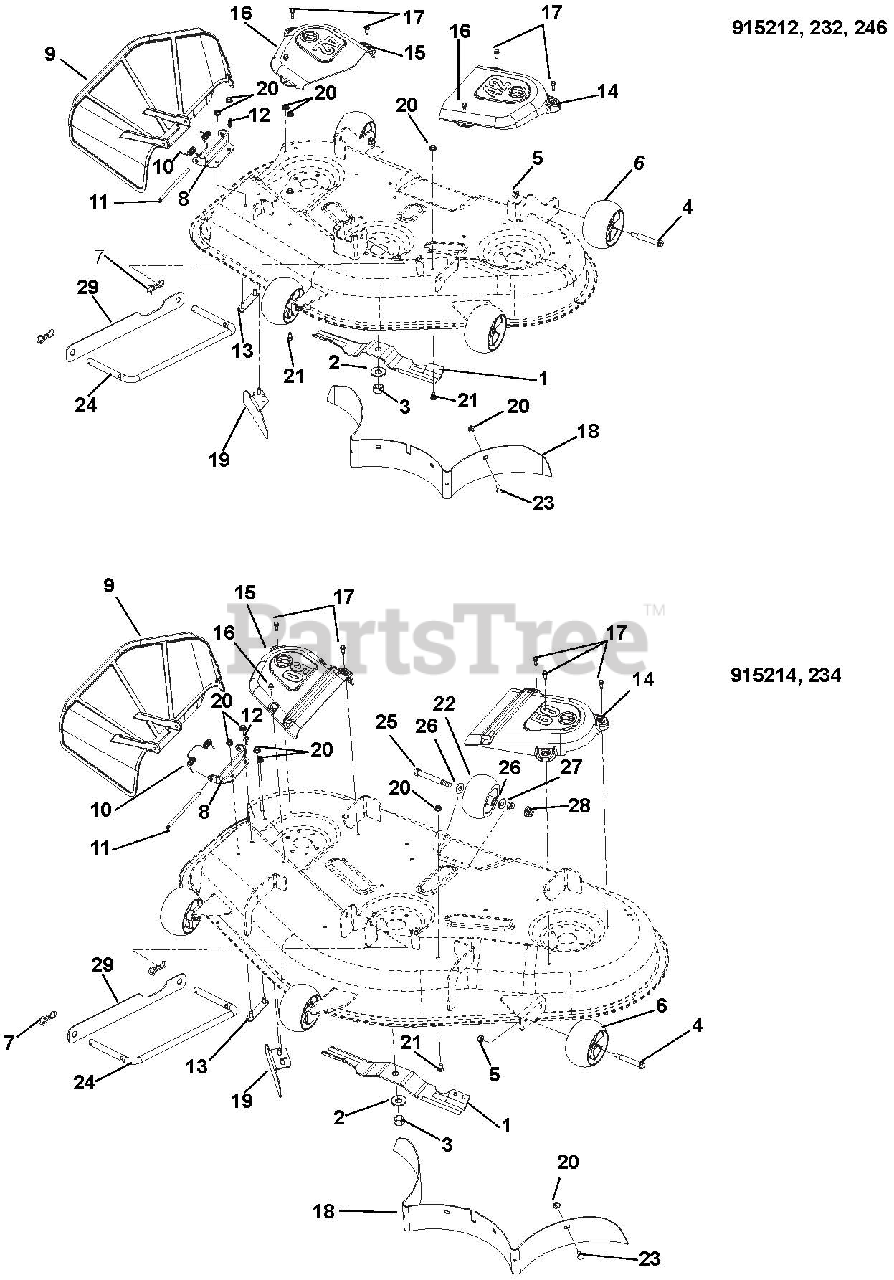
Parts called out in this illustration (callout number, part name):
1	BLADE, MOWER 14.83 (.188 THK)
1	BLADE, MOWER 17.35
2	WSHR-BLVL .669X1.535X.138
3	NUT-HEX .62-18 YWZC
4	BLT-SHLDR .38-16X2.50 HWH G5
5	@NUT-LK-TOP-FLG .38-16 YWZC
6	ANTI-SCALP WHEEL - 5X OS
7	PIN,BOW TIE LOCKING .091X1.875
8	BRKT-DISCHARGE CHUTE MOUNT 42"
8	BRKT, CHUTE MOUNT - 50"
9	CHUTE, DISCHARGE - MOLDED
10	SPRING-TORSION
11	PIN, 5/16 X 5.80"
12	PIN-HAIR INT .08X.18X1.18 YWZC
13	WMT-DISCHARGE CHUTE MT. STRAP
14	BELT COVER - LH 42"
14	BELT COVER - LH 50"
15	BELT COVER - RH 42"
15	BELT COVER - RH 50"
16	SCR-TAP .25-20X.50 HWH TR YWZ
17	SCR-TAP .25-20X.75 HWH TR YWZ
18	BAFFLE, REAR (42)
18	BAFFLE-50" STAMPED DECK REAR
19	WLDMT-BAFFLE, DISCHARGE 42"
19	BAFFLE, DEFLECTOR (50)
20	@NUT-LK-TOP-FLG .31-18 YWZC
21	@BLT-HEX .31-18X.50 GR5 YWZC
22	ROLLER
23	@BLT-RHDSSQNK .31-18X.75 G5YZ
24	WIREFORM, DRAG LINK
25	@BLT-HEX .38-16X3.50 GR5 YWZC
26	@WSHR-FL-STL.406X.812X.065 YWZ
27	@NUT-LK-CTR-JAM .375-16 YWZC
28	@NUT-LK-NYL-FLG .38-16 YWZC
29	STRAP, DRAG LINK
